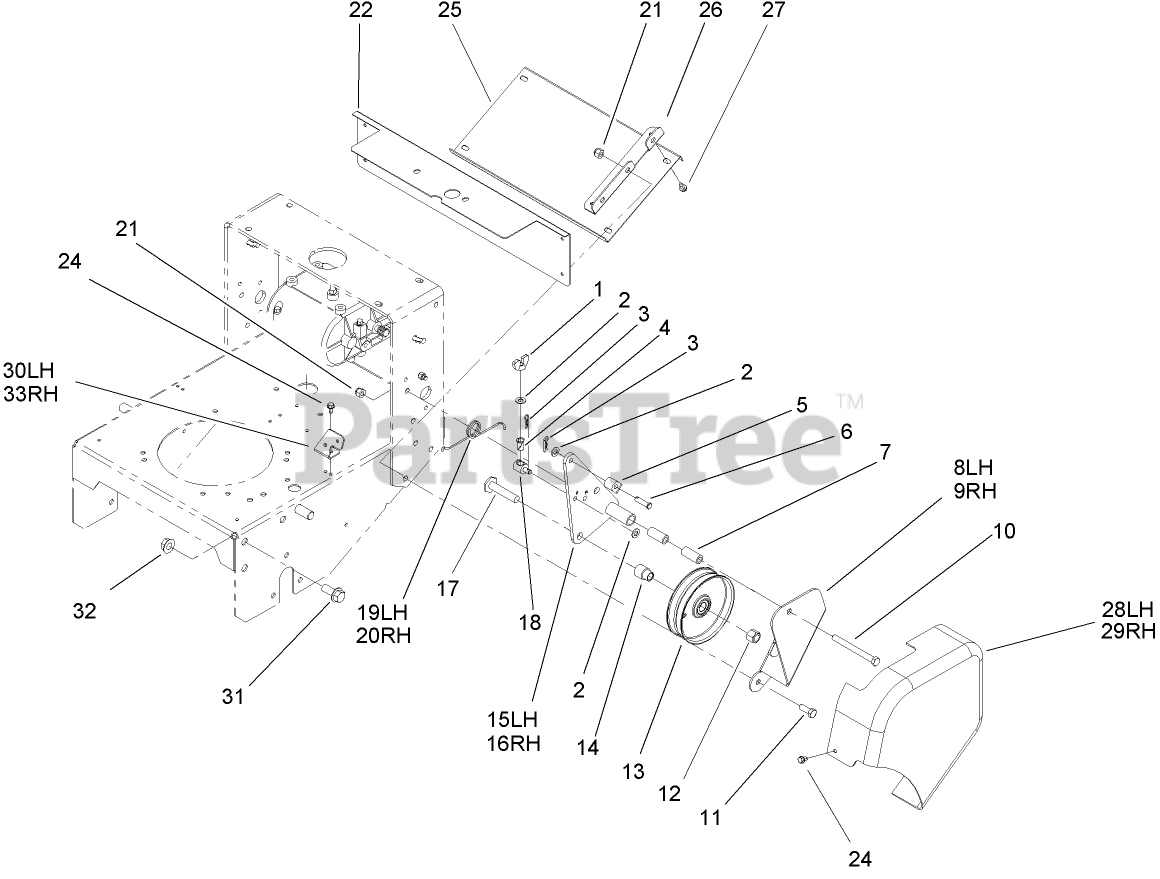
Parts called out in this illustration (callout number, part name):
1	NUT-WING
2	WASHER-PLAIN
3	PIN-COTTER
4	BUSHING-NYLON
5	FITTING-ROD
6	PIN-CLEVIS
7	SPACER-PIVOT, IDLER
8	BRACKET-SUPPORT, LH
9	BRACKET-SUPPORT, RH
10	SCREW-HH
11	SCREW-HH
12	NUT-LOCK, NI
13	PULLEY-IDLER
14	SPACER-PULLEY
15	BRACKET-IDLER, LH
16	BRACKET-IDLER, RH
17	SCREW-LEVELER
18	FITTING-ROD
19	SPRING-TORSION, LH
20	SPRING-TORSION, RH
21	NUT-LOCK, NI
22	GUARD-SHAFT, TRANSMISSION
24	SCREW
25	PANEL-BOTTOM
26	ANGLE-MOUNTING
27	SCREW
28	GUARD-BELT, LH
29	GUARD-BELT, RH
30	BRACKET-MOUNTING, LH
31	SCREW-HHF
32	NUT-HF
33	BRACKET-MOUNTING, RH
